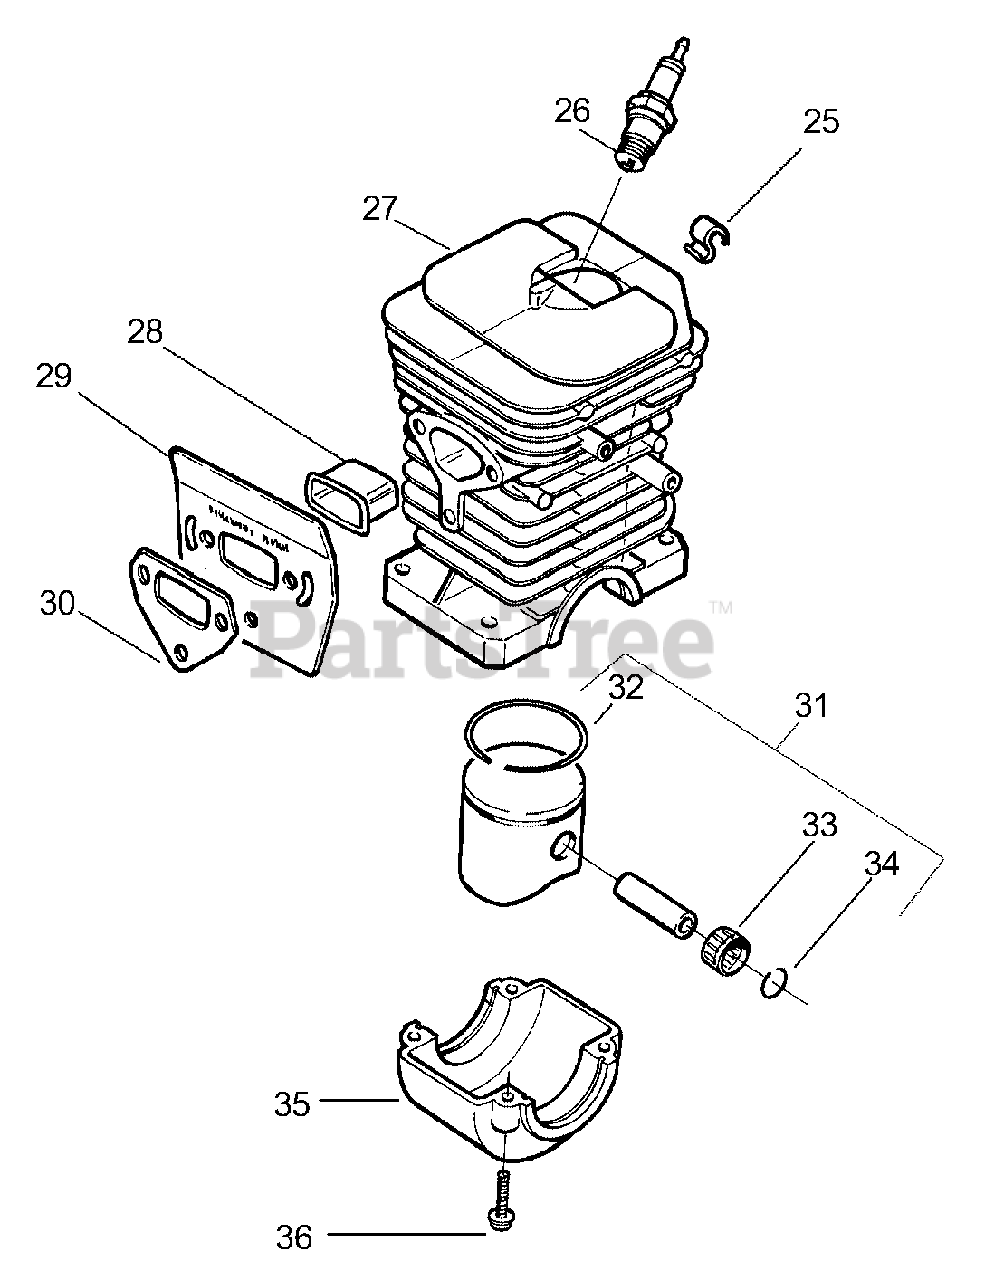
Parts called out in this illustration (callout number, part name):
26	Spark Plug (RCJ-7Y)
27	Kit-Cylinder (136)
27	Kit-Cylinder (141)
28	Heat Insulator
29	Muffler--Plate
30	Muffler Gasket
31	Piston Kit (136)
31	Piston Kit (141)
32	Piston Ring (136)
32	Piston Ring (141)
33	Piston Pin Bearing
34	Piston Pin Retainer
35	Cap--Crankcase
